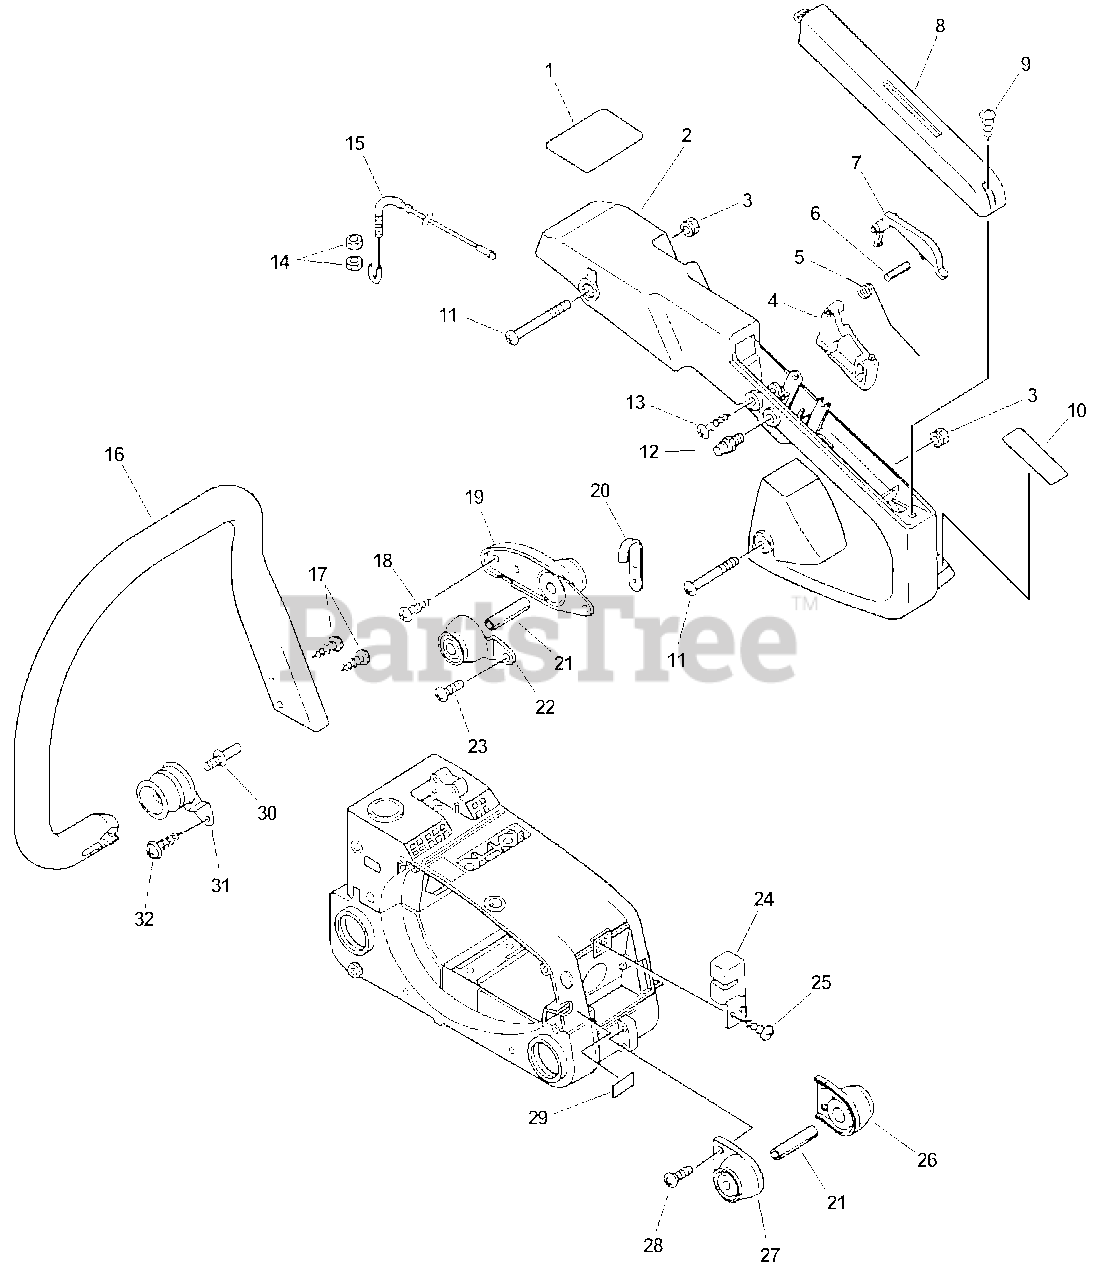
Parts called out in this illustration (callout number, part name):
1	LABEL, UL - KICK BACK
2	HANDLE, REAR
3	NUT, FLANGE M5
4	CONTROL, THROTTLE
5	SPRING, THROTTLE LOCKOUT
6	ROLLER, 4×19.8
7	LOCKOUT, THROTTLE
8	COVER, HANDLE
9	SCREW 4×22
10	LABEL - CAUTION
11	SCREW 5×57
12	LOCK, THROTTLE TRIGGER
13	SCREW 4×25
15	CABLE, THROTTLE
16	HANDLE, FRONT
17	SCREW, TAPPING 5×20
18	SCREW 4×10
19	CUSHION
21	COLLAR 5
23	SCREW 4×10
25	SCREW 4×14
28	SCREW 4×14
29	LABEL, STOP
31	CUSHION 5
32	SCREW 4×16
